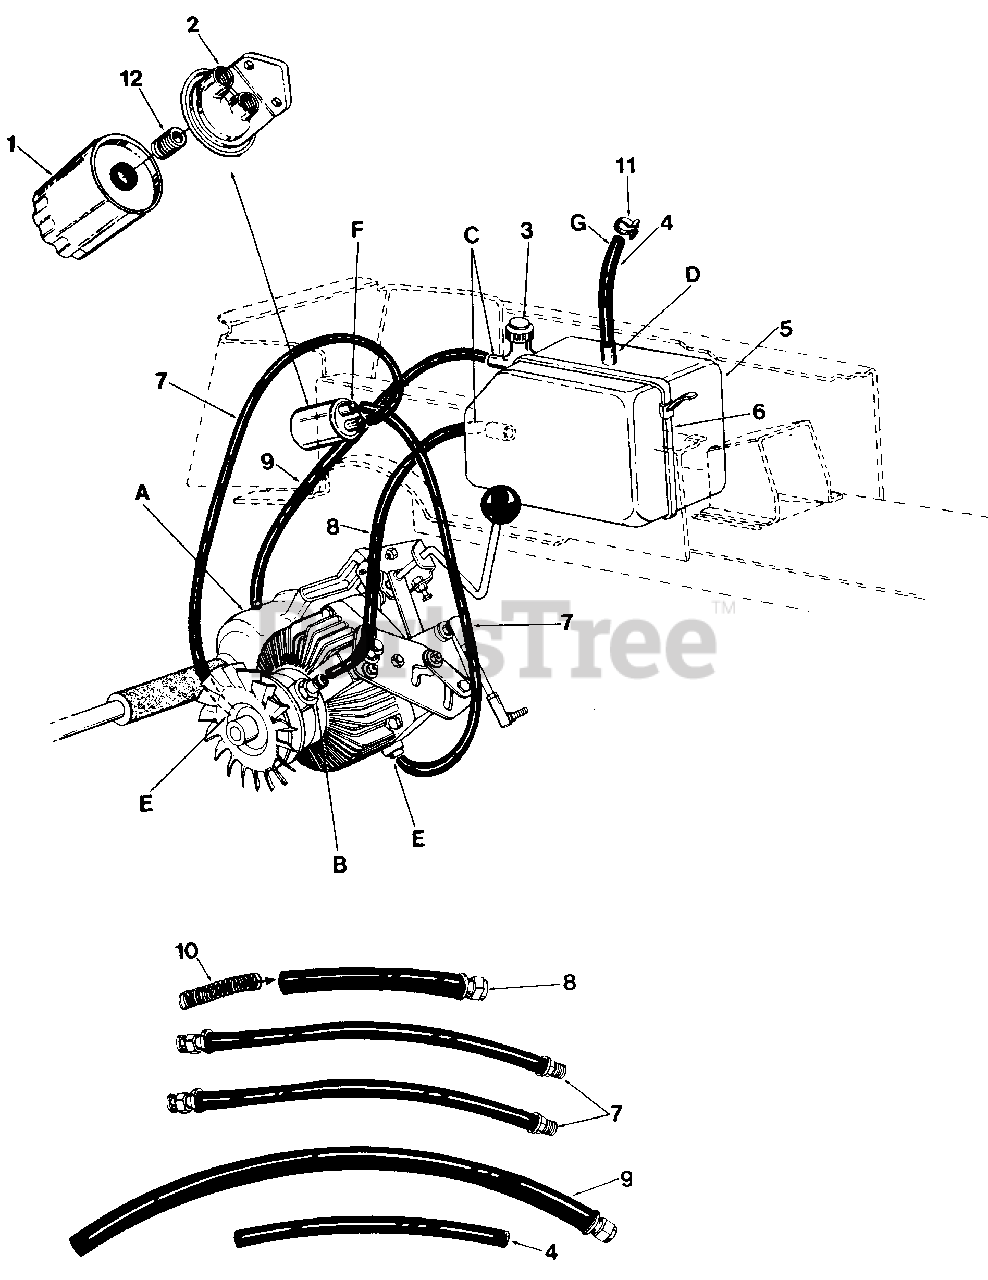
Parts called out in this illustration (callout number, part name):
1	Oil Filter
2	Filter Base
3	Oil Reservoir Cap
4	Gas Line-13" Lg.
5	Oil Reservoir
6	Cable Tie 34.25" Lg.
7	Hose Ass'y. 3/8" I.D. x 16.5" Lg.
8	Hose Ass'y. 5/8" I.D. x 9" Lg.
9	Hose Ass'y. 1/2" I.D.
11	Wire Retainer
12	Plug Expansion 13/16
A	7/8-14 SAE Boss to 3/4-16 JIC.
B	Adapter-"O"-Ring, Boss to Male JIC.
C	Hose Clamp .406 Dia. for Ref. No. 9
D	Hose Clamp 3/8" Dia.
E	1/2-20 SAE Boss to 1/2-20 JIC.
F	Pipe Reducer 1/2-14 to 3/8-18 NPT
G	Hose Clamp .37 Dia. Finish-Green Paint
